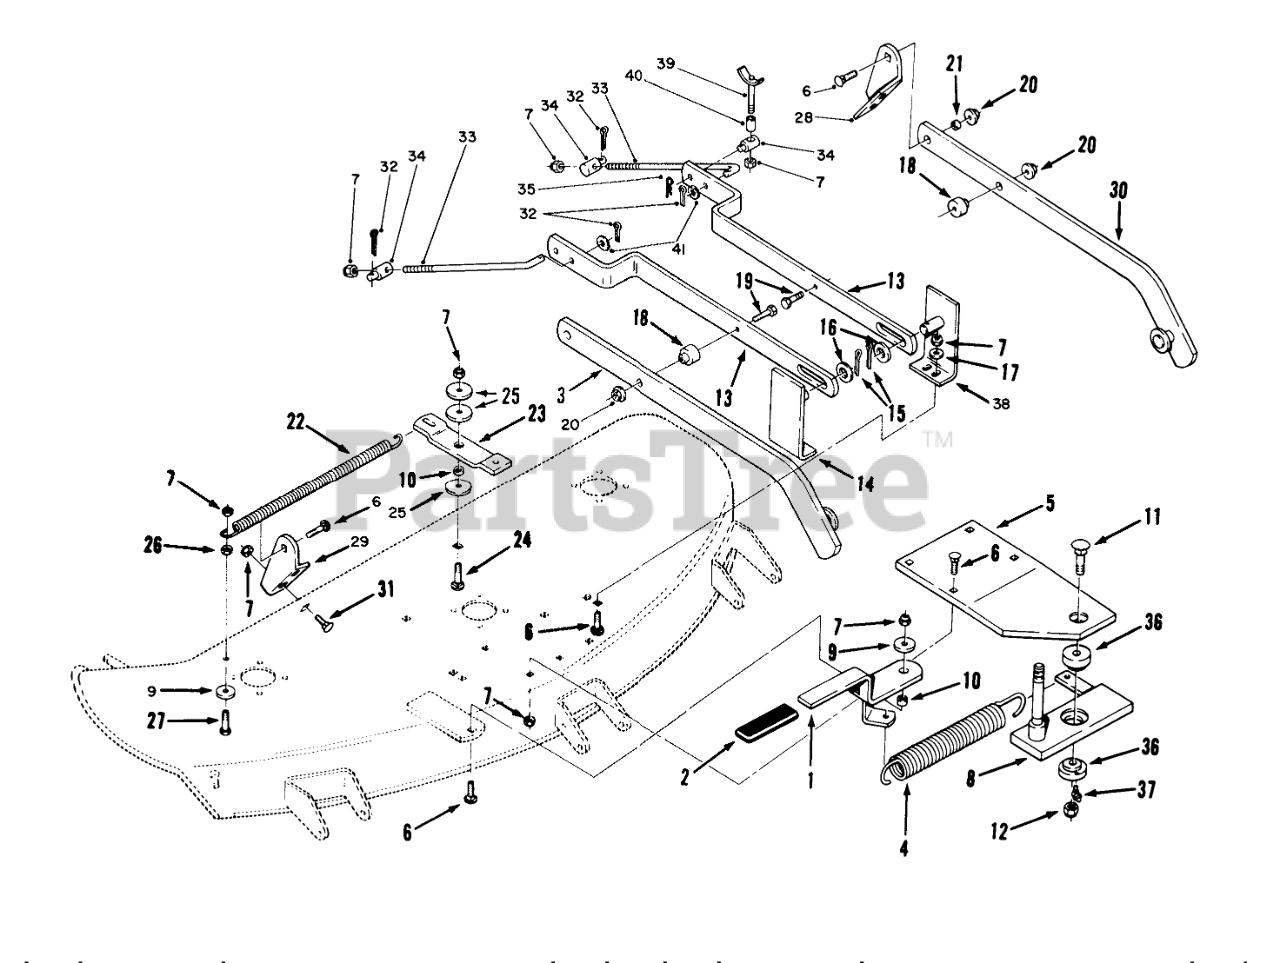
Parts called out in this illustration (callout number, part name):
1	Lever
3	Draft Bar RH
4	Spring
5	Plate
6	BOLT-CARR
7	NUT-LOCK, NI
8	Countershaft
9	WASHER
10	SPACER
11	Bolt
12	NUT-LOCK, NI
13	Bar-Leveler
14	Bracket L.H.
15	PIN-COTTER
16	WASHER-FLAT
17	WASHER-FLAT
18	SPACER
19	SCREW-HH
20	LOCKNUT-FLANGE
21	SPACER
22	SPRING - EXTENSION
23	Arm-Idler
24	SCREW-CARR
25	Washer
26	NUT-HEX
27	SCREW-HH
28	Bracket LH
29	Bracket RH
30	Draft Bar LH
31	BOLT-CARR
32	PIN-COTTER
34	TRUNNION
35	Hairpin Cotter
36	BUSHING
37	Fitting-Grease
38	Bracket R.H.
39	WLDMT-HANGER ROD
40	SPACER .375 ID X 1.6
41	WASHER-PLAIN
